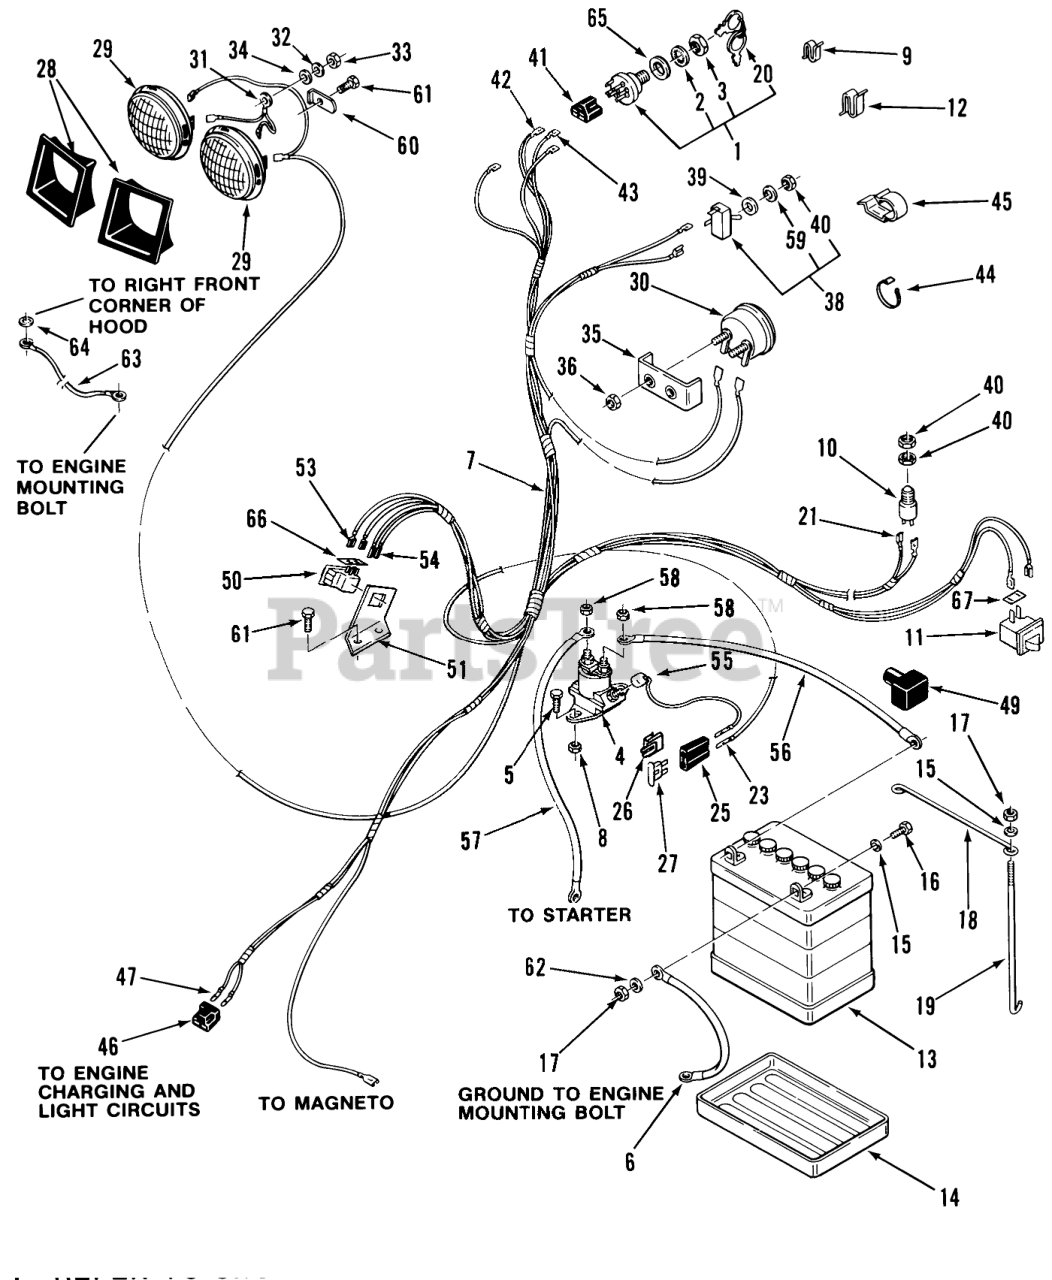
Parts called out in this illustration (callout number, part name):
1	ASSY-SWITCH IGNITION
2	LOCKWASHER
4	Solenoid
5	Screw
6	Wire
7	Wiring Harness Assy
8	Nut
9	SPEED CLIP
10	SWITCH-SEAT
11	SWITCH INTERLOCK
12	CLIP
13	Battery
14	TRAY BATTERY
16	Bolt
17	Nut
18	ROD-HOLD DOWN
20	Key-EL
21	Connector
23	TERMINAL-FUSE
25	AUTO-FUSEBLOCK TERM
27	FUSE-BLADE, 15 AMP
28	HEADLIGHT BEZEL ASSY.(SERVICE)
29	HEADLAMP
30	AMMETER W/CLAMP
31	LIGHT GROUND WIRE
32	Washer-Lock
33	Nut
34	WASHER 5/16 SAE
35	CLAMP
36	HEX NUT 10-32 E.S.
38	SWITCH-LIGHTS
39	TAB-WASHER
40	NUT-HEX
41	CONNECTOR-5 WAY-SERV
42	TERMINAL-TAB RCPT
43	Terminal
44	PLASTIC TIE
45	CLIP-WIRE
46	Conn Body Part of 7
47	Terminal
49	Boot
50	PTO Interlock Switch
51	BRACKET-SWITCH (NS)
53	Terminal
54	Wire Terminal (Part of 1)
55	Terminal Part of 5
56	Cable
57	Wire
57	Starter To Solenoid Cable 16.0 in. (40.6 cm) 216-5 Only
58	Nut
59	Washer
60	LOCK-HEADLIGHT
61	Bolt
62	Washer
63	WIRE GROUND
64	Washer-Lock
65	Washer
66	SHIELD-DIRT (DPDT)
67	SHIELD-DIRT SPST
